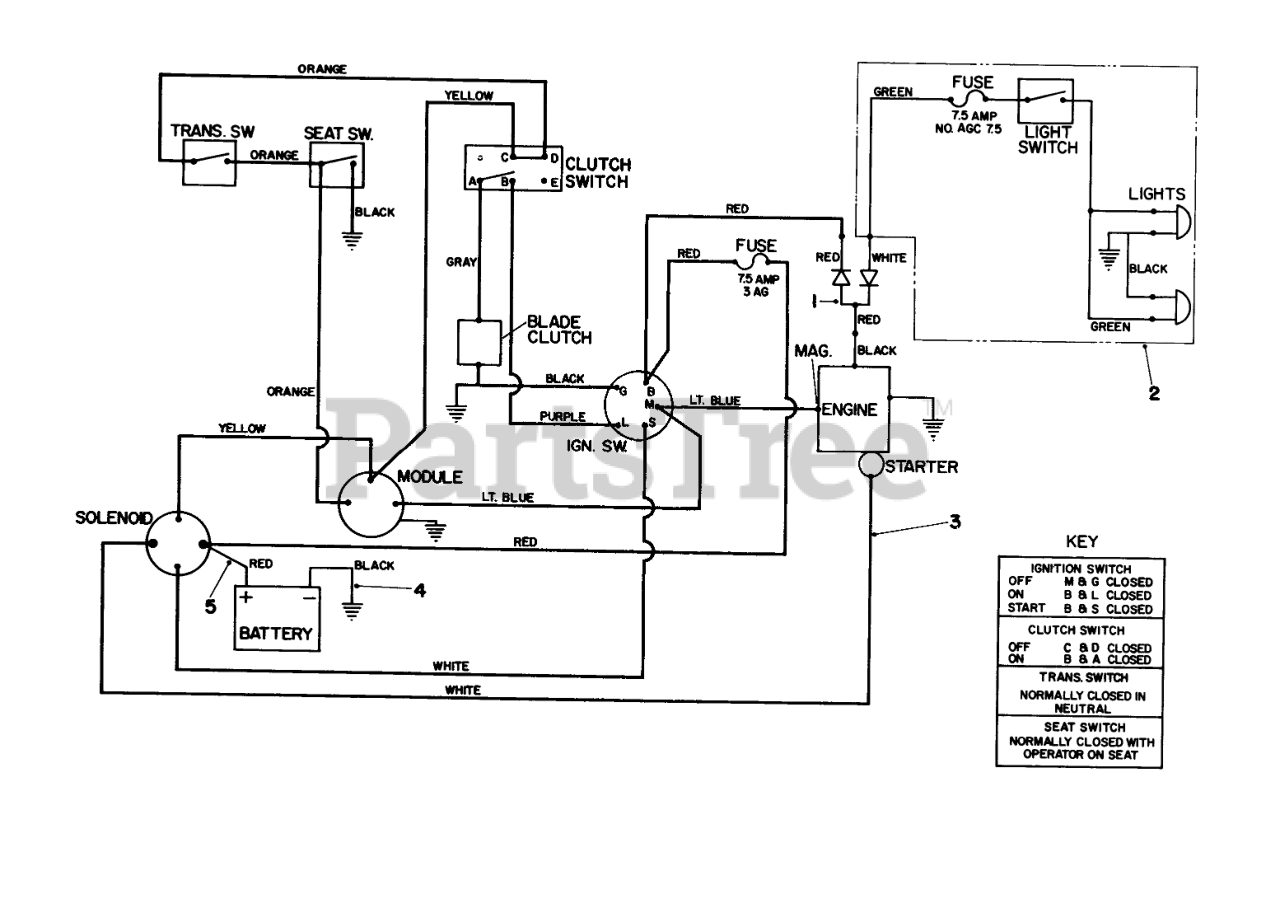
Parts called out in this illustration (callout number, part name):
1	WIRE HARNESS WIRE
2	WIRE HARNESS - LIGHTS
3	Wire Harness
4	WIRE ASM
5	WIRE ASM
